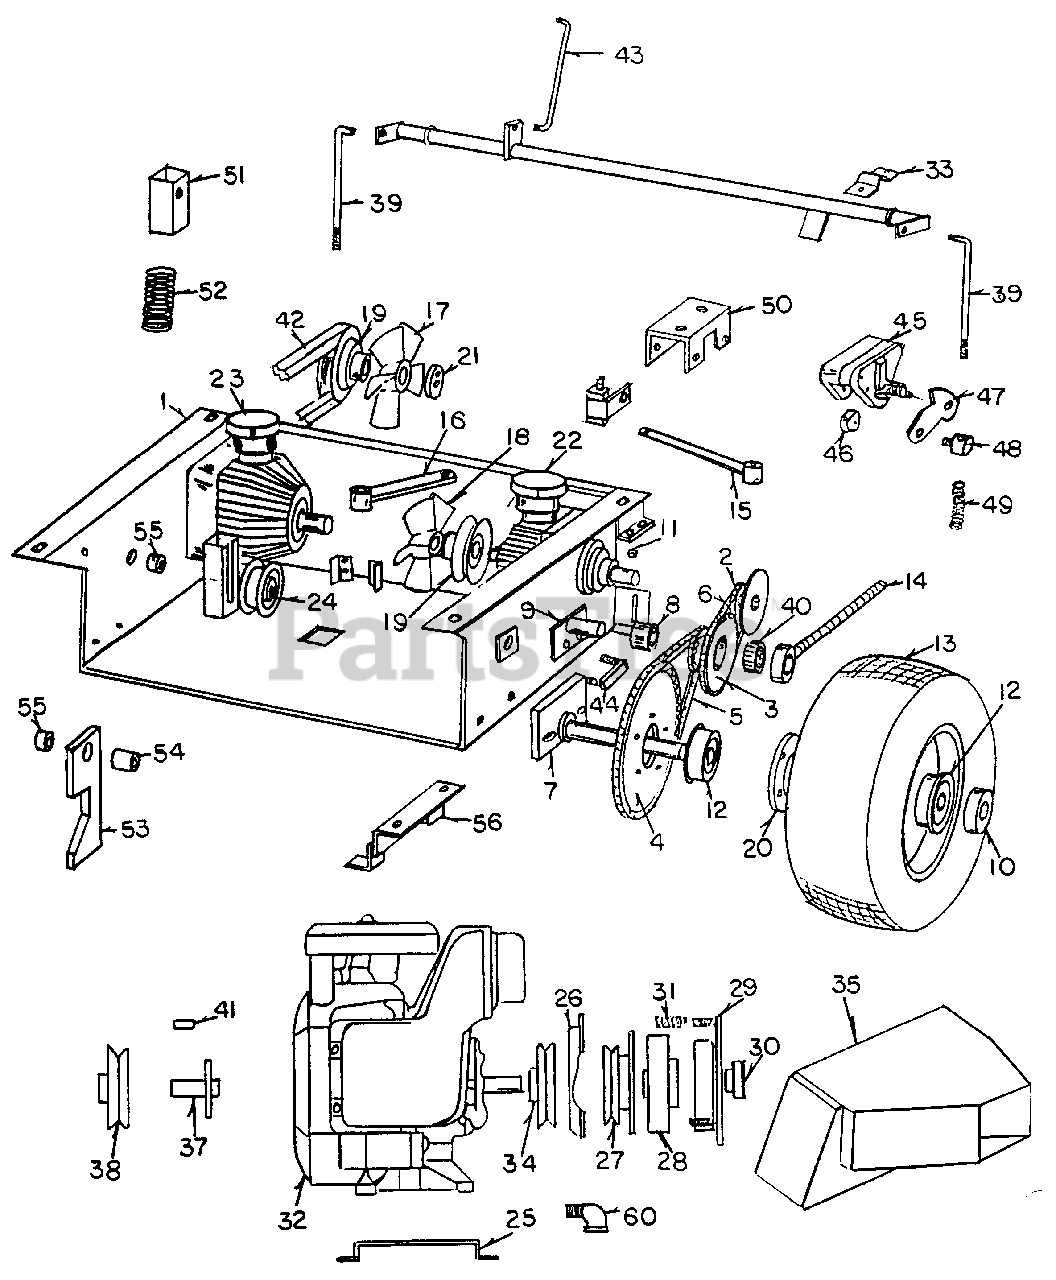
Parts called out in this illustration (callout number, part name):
1	G Base
2	Sprocket w/ Disc Brake
3	Primary Drive Sprocket
4	Final Drive Sprocket
5	Final Drive Chain
6	Primary Drive Chain
7	Drive Wheel Axle
8	Short Idler Sprocket Bearing
9	Idler Sprocket Shaft
10	Drive Axle Set Collar
11	Transmission Key
12	Drive Wheel Bearing
13	Drive Wheel Assembly
14	Support Collar
15	Transmission Arm L.H.
16	Transmission Arm R.H.
17	Transmission Fan R.H.
18	Transmission Fan L.H.
19	Transmisdon Pulley
20	Wheel Hub
21	Transmission Washer
22	Transmission L.H.
23	Transmission R.H.
24	Idler Pulley
25	11 HP Adapter Plate
27	Clutch Armature
28	Clutch Rotor
29	Clutch Coil
30	Clutch Retainer
32	Briggs/Stratton 11 HP
33	Brake Cross Rod Bearing
34	Transmission Drive Pulley
35	Air Duct
40	Long Idler Sprocket Bearing
41	Key Stock
42	Transmission Belt
43	Brake Rod
45	Brake Caliper
47	Caliper Lever L.H.
48	Caliper Rod Collar
49	Caliper Spring
50	Caliper Bracket
51	Spring Loaded Idler Mount
53	Forward Nose Down Lock
54	Bushing, Long
55	Bushing, Short
56	Electric Clutch Stop
60	3/8" Elbow
